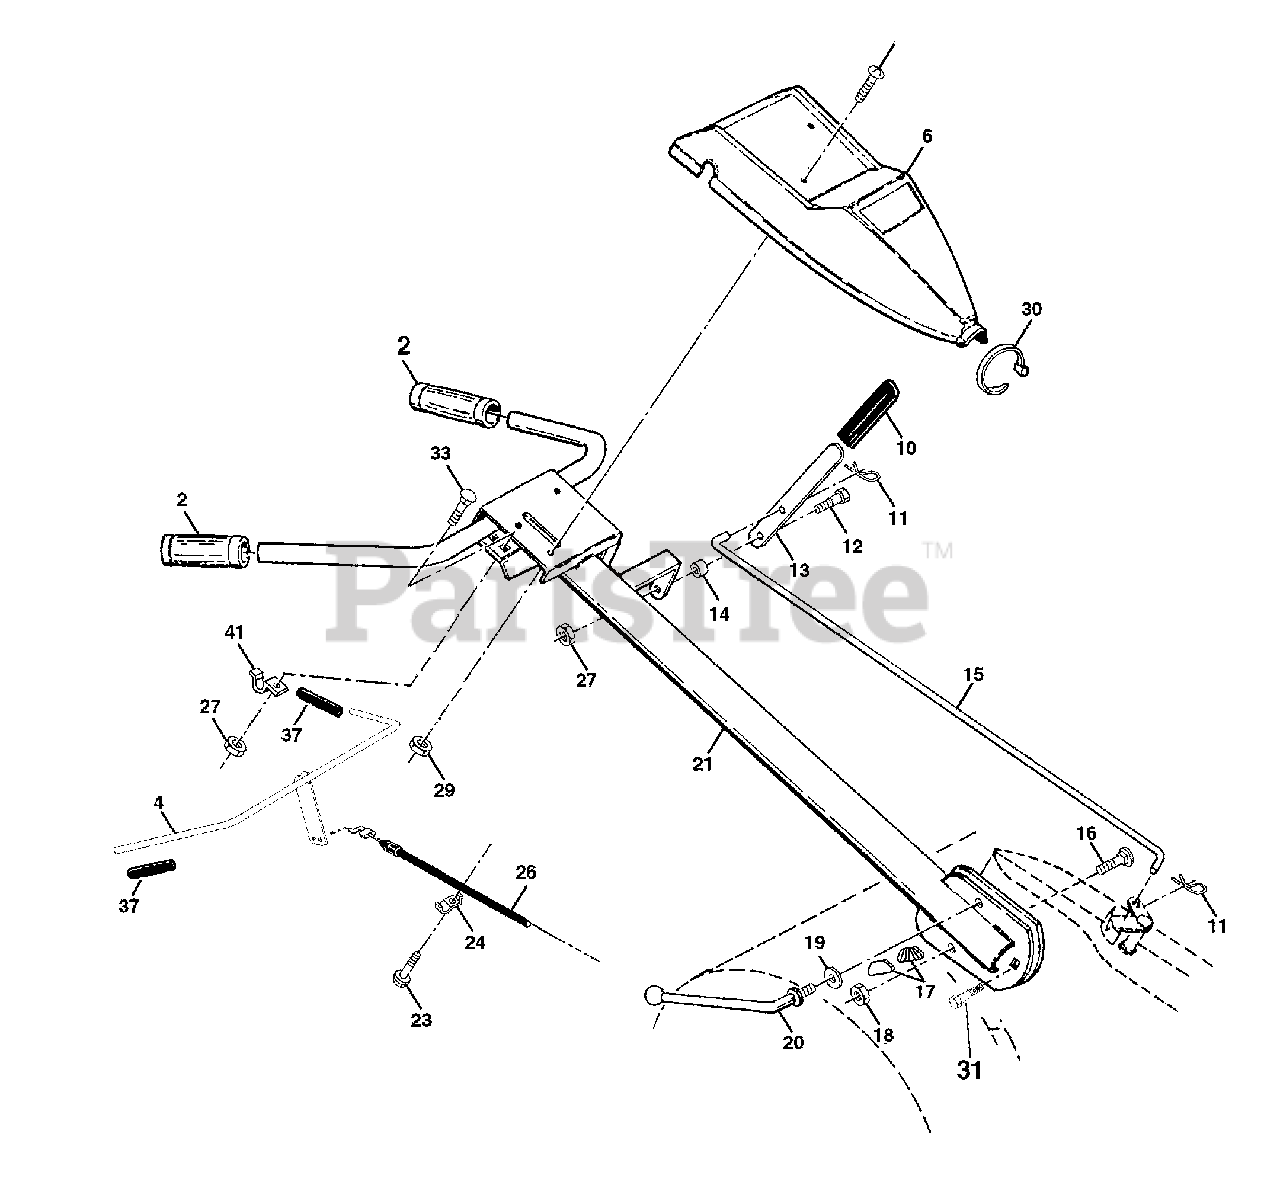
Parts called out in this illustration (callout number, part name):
2	Grip, Handle
4	Bar Assembly, Control
6	Panel, Control
8	Screw, Phd. #10-24
10	Grip, Handle
11	Clip, Hairpin
12	Bolt, Shoulder
13	Handle, Shift
14	Grommet, Rubber
15	Rod, Shift
16	Bolt, Carriage 3/8-16 x 1 Gr. 5
17	Lock, Handle
18	Nut Crownlock 3/8-16 UNC
19	Washer 13/32 x 1 x 11 Ga.
20	Lever, Lock, Handle
23	Screw, Hex Washer Hd. Slotted
24	Clip
26	Cable, Clutch #10-24 x 1/2
27	Nut Hexflange 1/4-20 UNC
29	Nut, Keps #10-24 UNC
30	Tie, Cable
31	Bolt, Pivot
33	Bolt, Carriage 1/4-20 UNC x 1/2
37	Grip, Bar, Control
41	Clamp, Bar, Control
